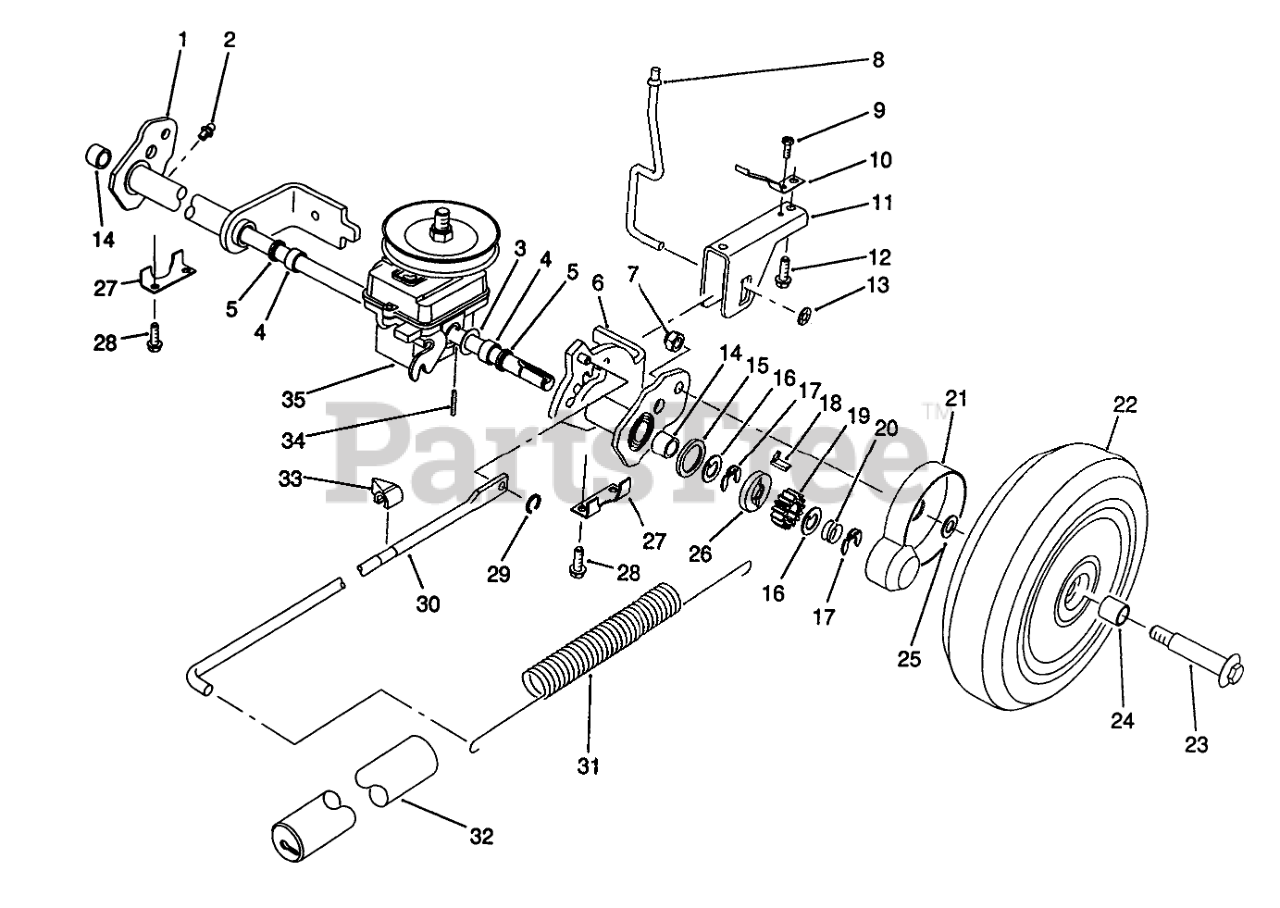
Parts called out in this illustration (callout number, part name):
1	Rear Pivot Assembly R. H. (Incl. Ref. #2, 4, 5 & 14)
2	Fitting-Grease
3	WASHER-PLAIN
4	BUSHING
5	SEAL-OIL
6	Rear Pivot Assembly L.H. (Incl. Ref. #2, 4, 5 & 14)
7	Nut
8	TRIGGER ROD
9	SCREW 8 - 32 X 250
10	SPRING - TRIGGER RET
11	SADDLE - HOC
12	SCREW
13	PUSHNUT
14	BEARING-ROLLER
15	RING-FRICTION
16	WASHER-THRUST, KEYED
17	RING-CLIP, LOCKING
18	KEY-ROCKING, LH
19	GEAR-PINION
20	SPRING-COMPRESSION
21	COVER-WHEEL
22	Wheel, Tire & Gear Assy. (Incl. Ref. #24)
23	BOLT-WHEEL
24	BUSHING
25	SPACER-COVER, WHEEL
26	WASHER-CLUTCH
27	REAR SECURING PLATE
28	SCREW-HWHTF
29	GRIP RING
30	LINK ROD
31	SPRING-COUNTERBALANCE
32	COVER-SPRING
33	INDICATOR-HEIGHT OF CUT
34	COIL PIN
35	Gearbox Assembly
